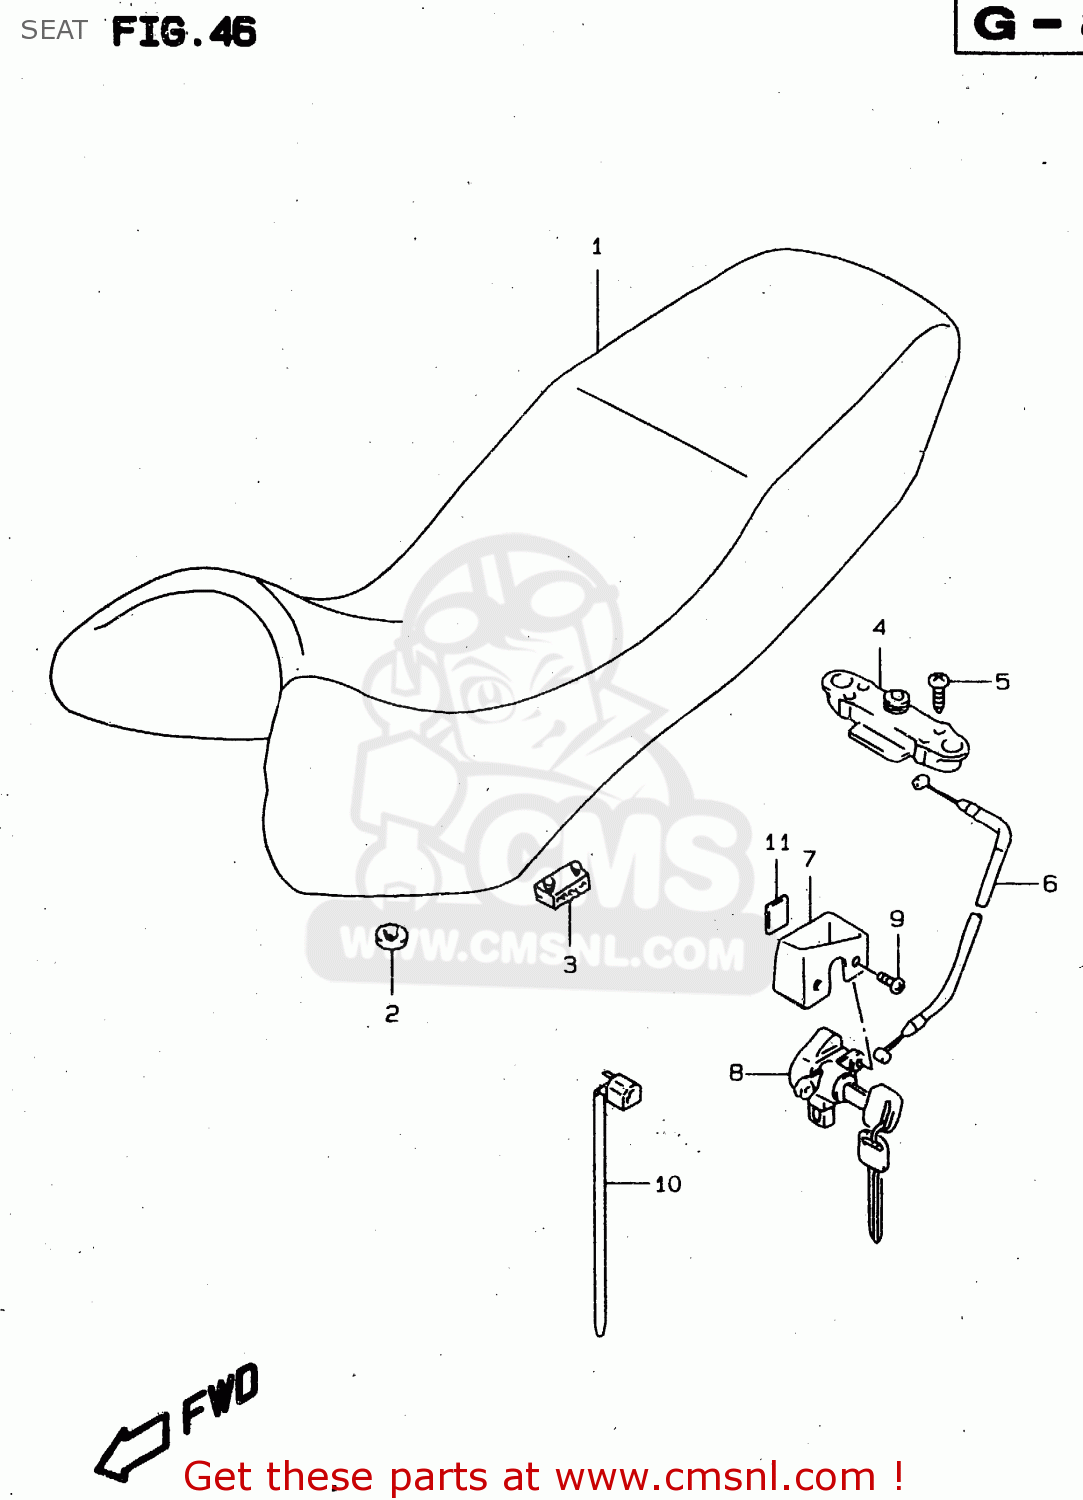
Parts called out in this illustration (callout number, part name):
1	SEAT SET
2	CUSHION,SEAT
3	CUSHION,SEAT(40X20X15)
4	LOCK ASSY,SEAT STRIKER
5	SCREW 6X30
6	CABLE,SEAT LOCK
7	GUARD, SEAT LOCK
8	LOCK SET,SEAT & HELMET
9	SCREW(6X14)
10	CLAMP(L:165)
11	CUSHION
